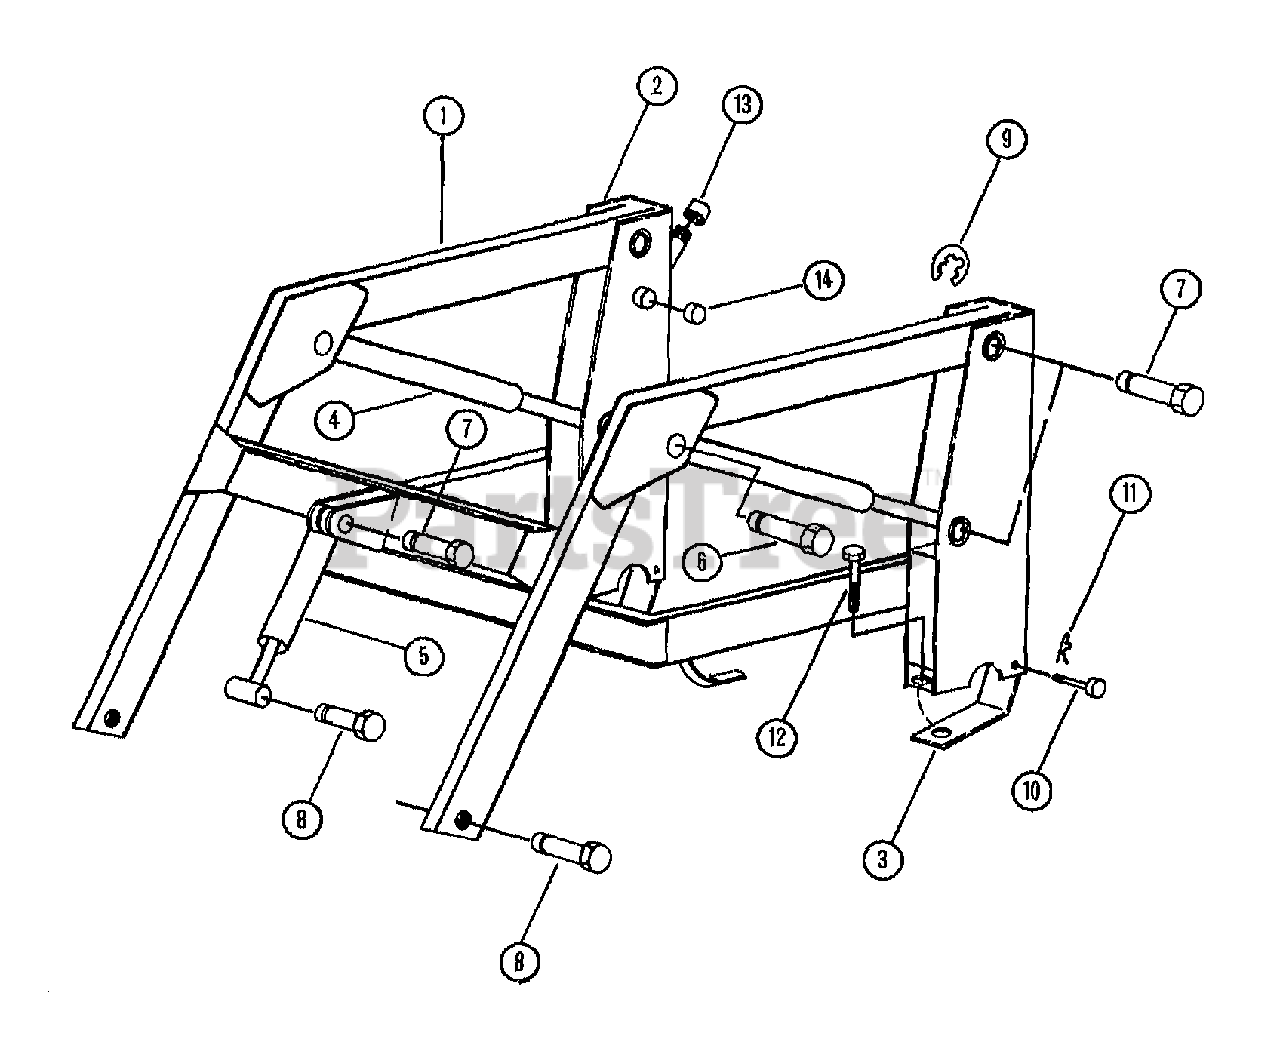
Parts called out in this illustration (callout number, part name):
1	ASSM-BOOM
2	ASSM-SUBFRAME
3	ASSM-HINGE
4	CYLINDER-LIFT
5	BUCKET-CYLINDER
6	PIN-PIVOT
7	PIN-PIVOT
8	PIN-PIVOT
9	CLIP-PIVOT PIN
11	CLIP-HAIRPIN .07 DIA
